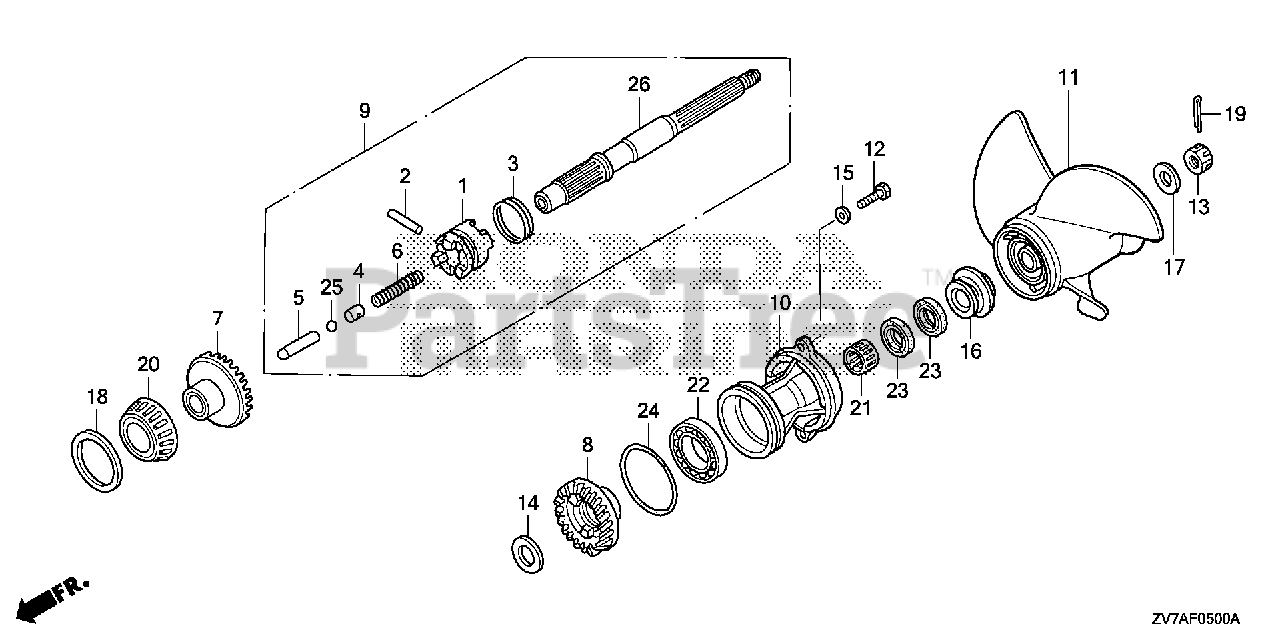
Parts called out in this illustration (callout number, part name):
1	SHIFTER, CLUTCH
2	PIN, SHIFTER
3	RING, CROSS PIN
4	HOLDER, SHIFTER PIN
5	SLIDER, SHIFT
6	SPRING, SHIFT
7	GEAR, FR. BEVEL
8	GEAR, RR. BEVEL
9	SHAFT ASSY., PROPELLER
10	HOLDER, PROPELLER SHAFT *NH282MU* (OYSTER SILVER METALLIC-U)
11	PROPELLER, THREE-BLADE (9-1/4X12) *NH283* (STIN GRAY)
12	BOLT, HEX. (6X20)
13	NUT, CASTLE
14	WASHER (22MM)
15	WASHER, PLAIN (6MM)
16	WASHER, PROPELLER THRUST
18	SHIM, FR. BEVEL (51X57X0.10) (A)
18	SHIM, FR. BEVEL (51X57X0.15) (B)
18	SHIM, FR. BEVEL (51X57X0.30) (C)
18	SHIM, FR. BEVEL (51X57X0.50) (D)
19	PIN, SPLIT
20	BEARING (32X58X17)
21	BEARING, NEEDLE (22X28X20)
22	BEARING, RADIAL BALL (32X58X13) (KOYO)
23	SEAL, WATER (22X35X7)
24	O-RING (64X3)
25	BALL, STEEL (#11) (11/32)
26	SHAFT, PROPELLER
